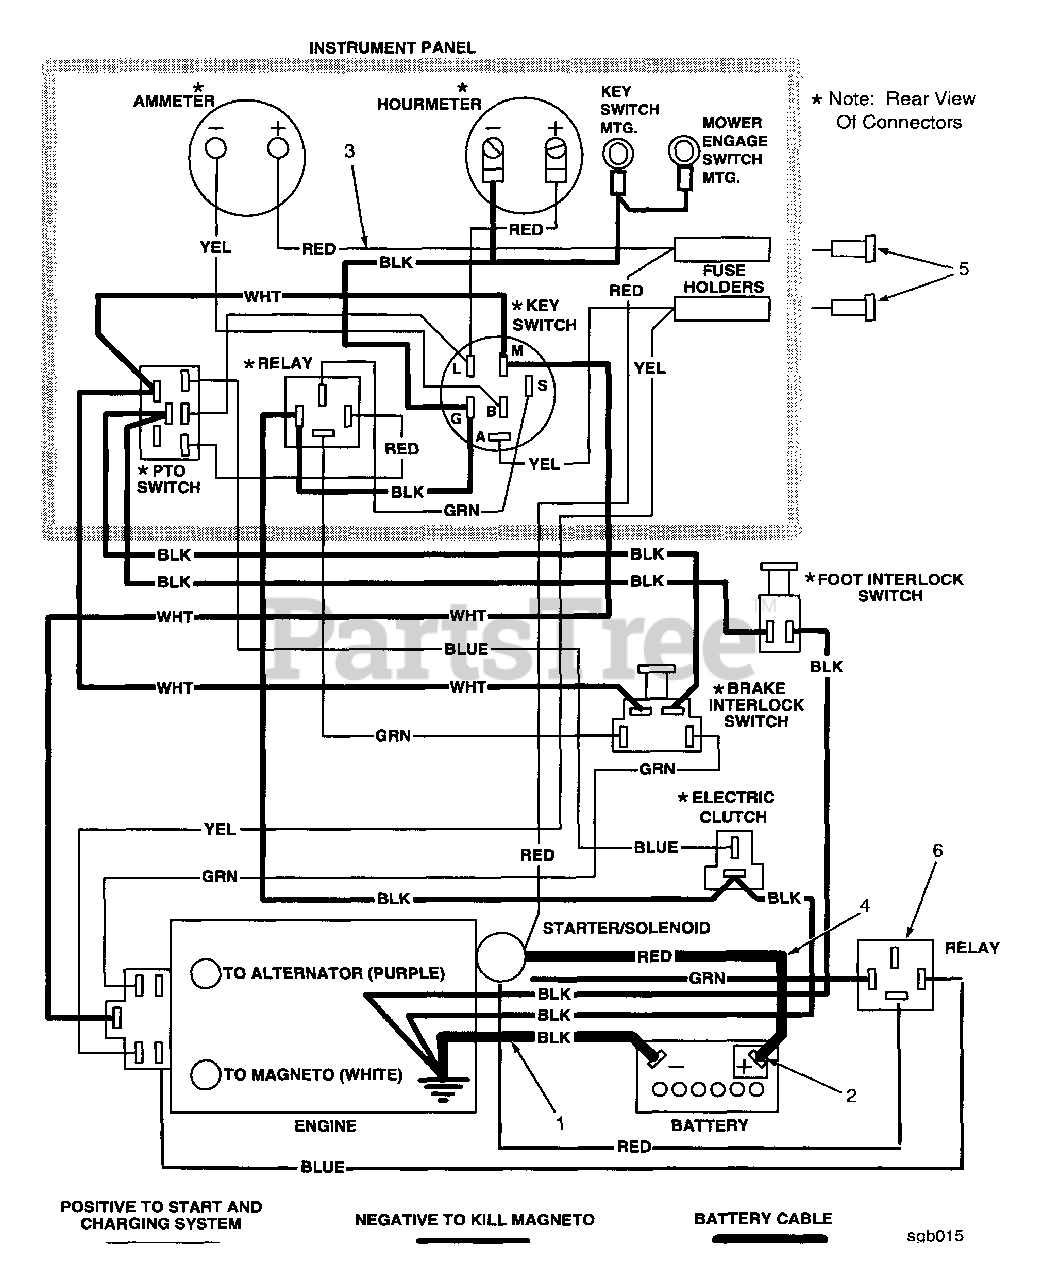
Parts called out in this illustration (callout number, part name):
1	Battery Cable, 36" Black
2	Rubber Boot
3	Wire Harness, STHM
4	Battery Cable, 25" Red
5	Fuse, 20 AMP Blade Automotive
6	Wire Harness With Relay
